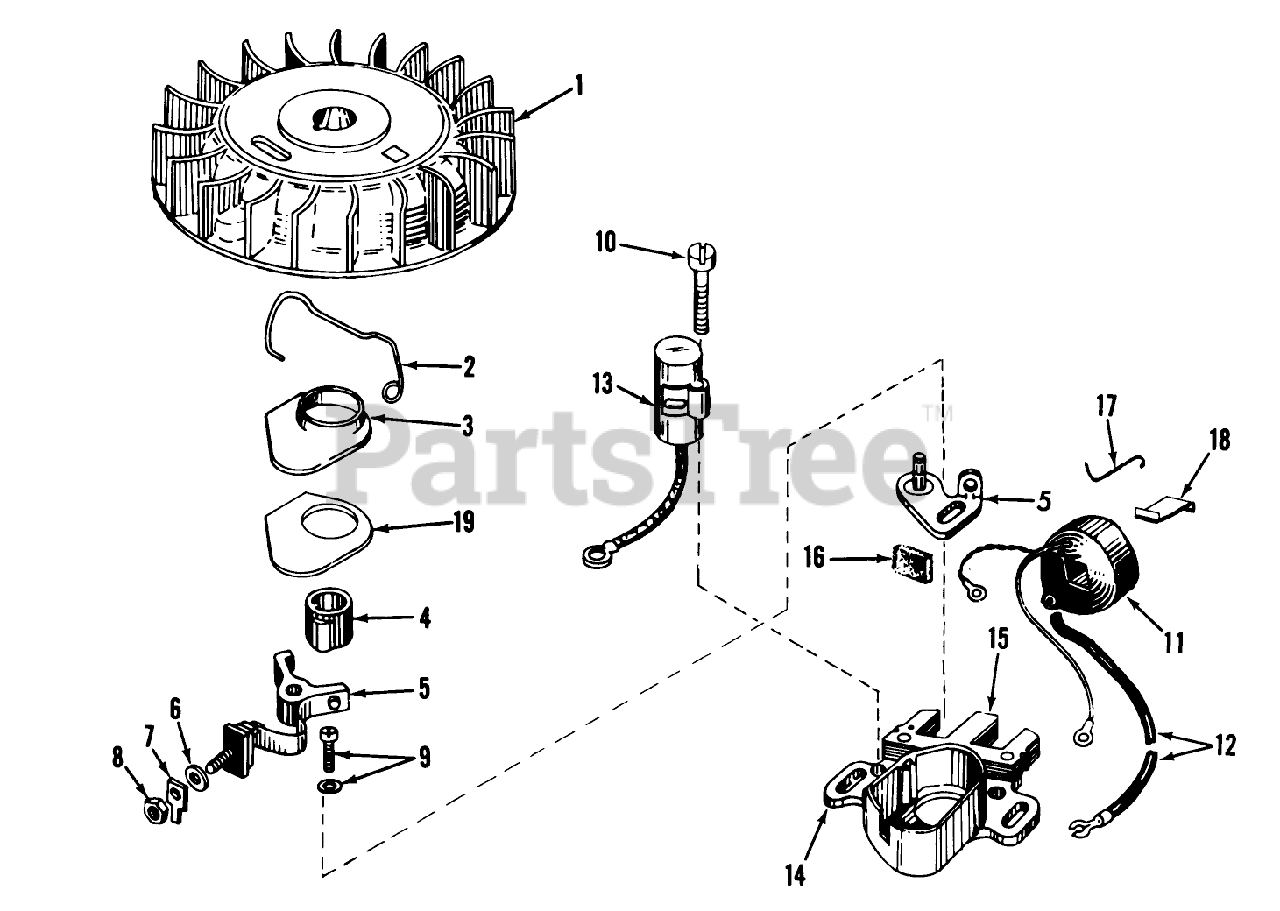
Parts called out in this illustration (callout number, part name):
1	Flywheel
2	Spring Breaker Box
3	Cover, Dust
4	Cam, Breaker
5	Breaker Assy.
6	Washer
7	Terminal
8	DECAL
9	Breaker Screw
10	Condenser Screw
11	Coil Assy., (Inc. Ref. Nos. 12, 13 18)
12	Wire, Lead
13	Condenser
14	Core Plate
15	Stator Assy., (Incl. Nos. 2, 3, 5 thru 14 16 thru 19)
16	Felt,Cam Wiper
17	Clip, Coil
18	Spring Coil Wedge
19	Gasket Dust Cover
